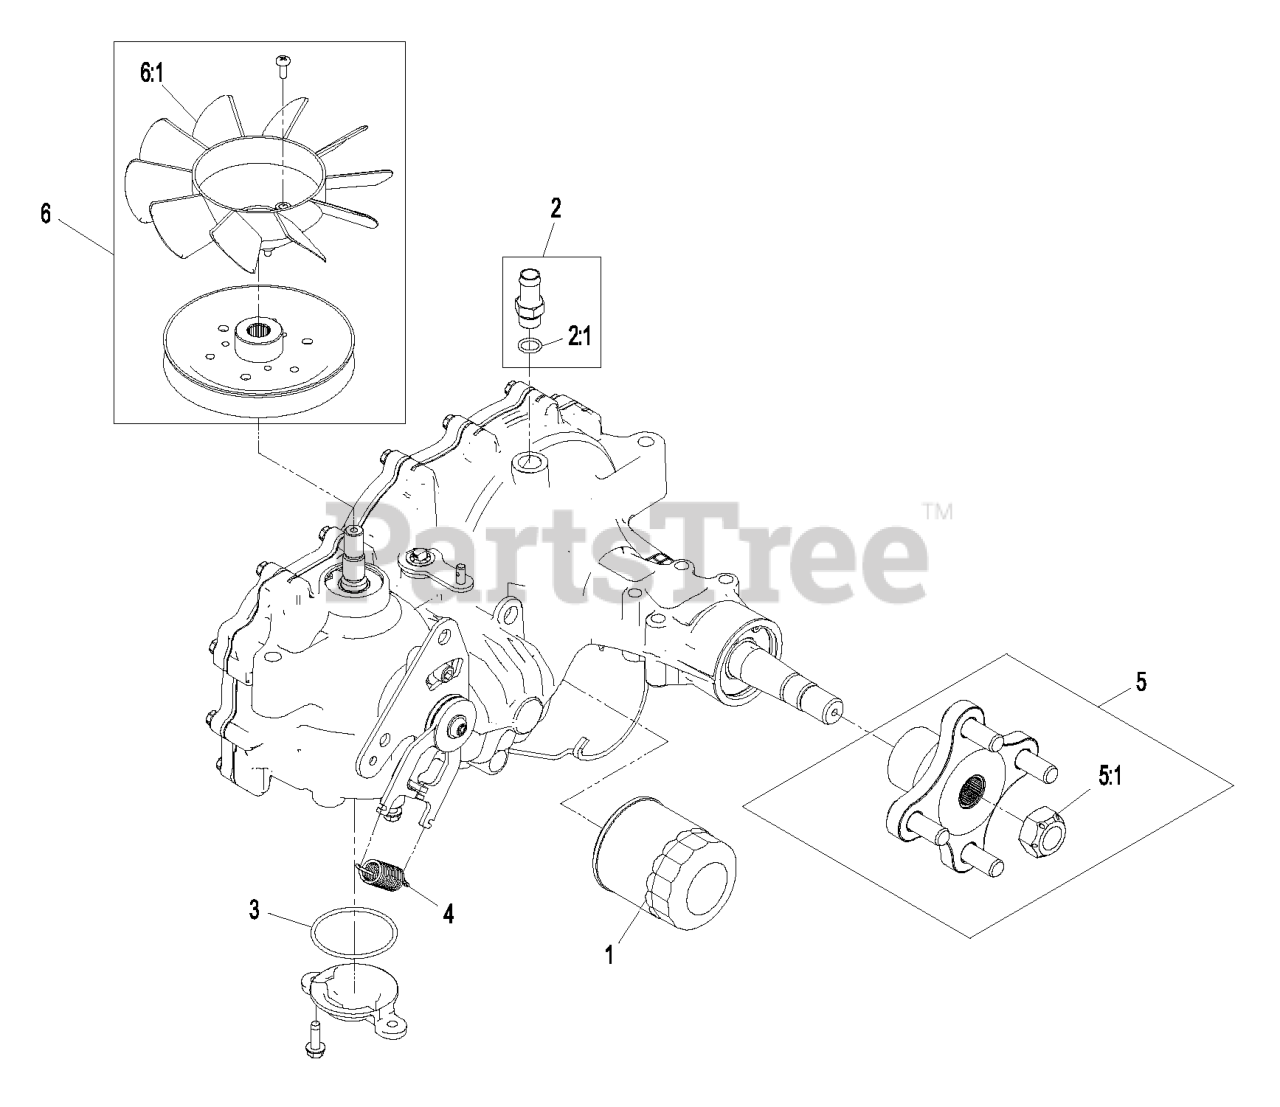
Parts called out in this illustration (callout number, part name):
1	ELEMENT-OIL FILTER, HYD
2	ADAPTER-STRAIGHT
2:1	BOSS O-RING
3	O RING-SEAL
4	SPRING-EXTENSION
5	HUB KIT
5:1	NUT-HUB
